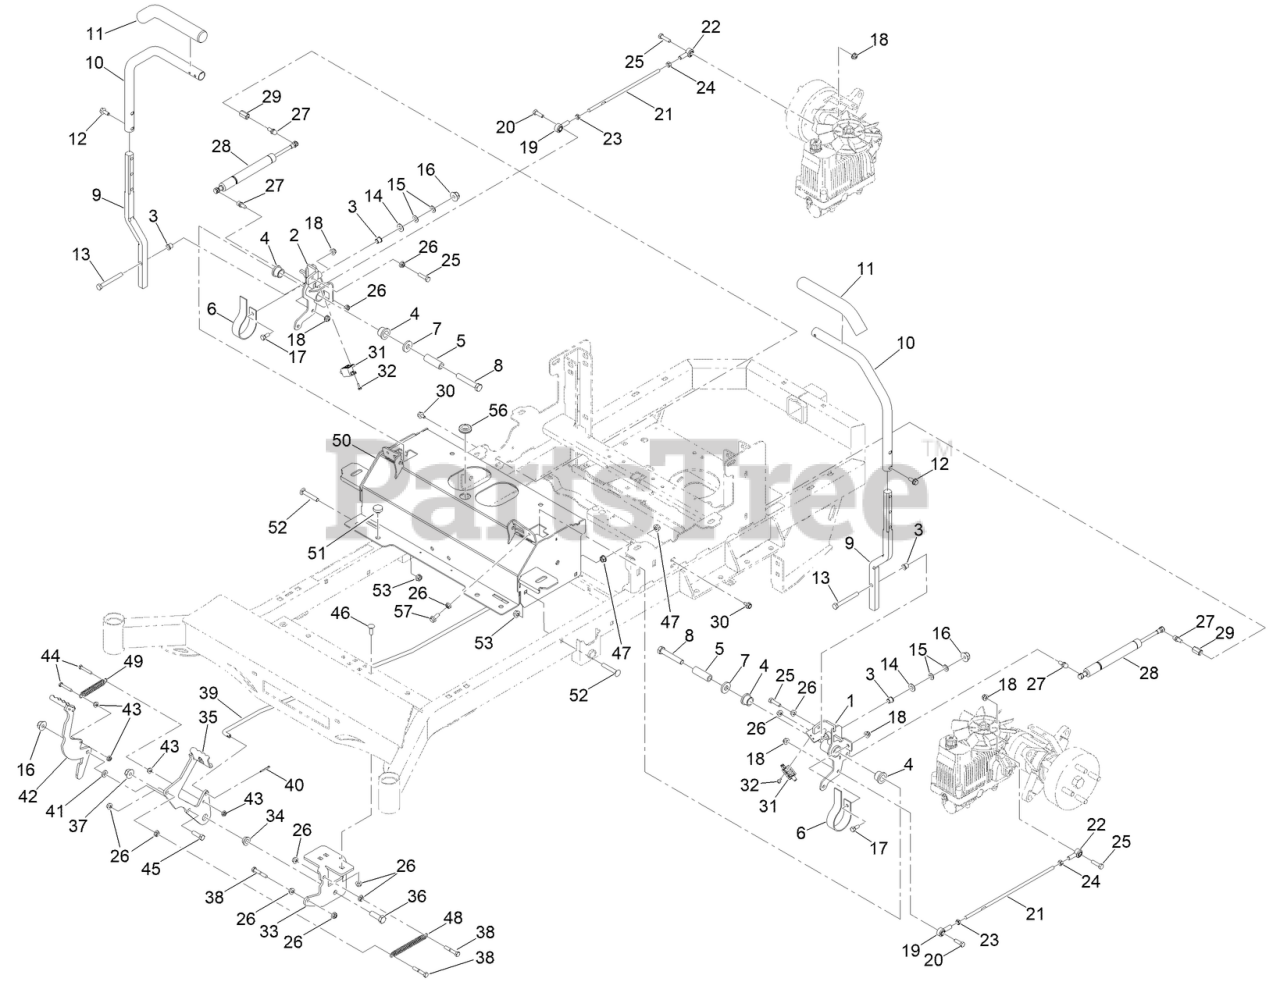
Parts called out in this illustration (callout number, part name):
1	LH PIVOT ASM
2	RH PIVOT ASM
3	BUSHING-FLANGE
4	BUSHING-FLANGE
5	SLEEVE-PIVOT
6	SPRING-LEAF
7	1/2 FENDER WASHER 1-1/4IN OD ZINC
8	1/2-13 X 3 HEX C/S GR 5 ZINC W/LOCTITE
9	HEIGHT ADJUSTABLE CONTROL ARM
10	MOWER DRIVE HANDLE TUBE ABC
11	CONTROL ARM HANDLE GRIP
12	SCREW-HHF
13	SCREW-HH
14	WASHER-FLAT
15	WASHER-BELLEVILLE
16	3/8-16 NYLON INSERT FLANGE L/NUT YZ
17	SCREW-HH
18	NUT-HF, NI
19	5/16-24 SPHER ROD END ZINC LH THD FEM
20	SCREW-HH
21	1310 TTQ DRIVE ARM ROD
22	5/16-24 SPHER ROD END ZINC RH THD FEM
23	NUT-JAM
25	SCREW-HH
27	5/16-18X1.286 DAMPER BALL STUD (.562 TL)
28	CONTROL ARM DAMPER
29	STANDOFF-HEX
30	SCREW-HHF
31	NO PLUNGER LIMIT SWITCH
32	8-32 X 1/2 IND. HWH SLOT TYPE F TCS ZINC
33	MWR FRAME BRAKE MTG BRKT PAINT
34	1/2IN ID X 3/4IN OD X 3/8IN FLANGE BUSH
35	MWR BRAKE LOCK LEVER ASSY PAINTED
36	SCREW-HH
37	NUT-LOCK
39	MWR BRAKE LINKAGE
40	PIN-COTTER
41	3/8 ID X 3/4 OD X .125 THK BRONZE WASHER
42	MWR BRAKE UNLOCK LEVER ASSY PAINTED
43	1/4-20 HEX FLANGE NUT
44	1/4-20 X 1-1/4 HEX C/S GR 2 ZINC
45	SCREW-HH
46	BOLT-CARR
47	3/8-16 HEX FLANGE NUT W/SERR ZINC YELLOW
48	2020 MWR BRAKE PEDAL TENSION SPRING
49	MWR BRAKE PEDAL RELEASE SPRING
50	ASM, GT-TRAC [GRAY]
51	PUSH-IN RUBBER BUMPER MWR FLOOR
52	SCREW-CARR
56	GROMMET-RUBBER
57	5/16-18 X 3/4 HEX FLANGE BOLT GR 8 YZ
